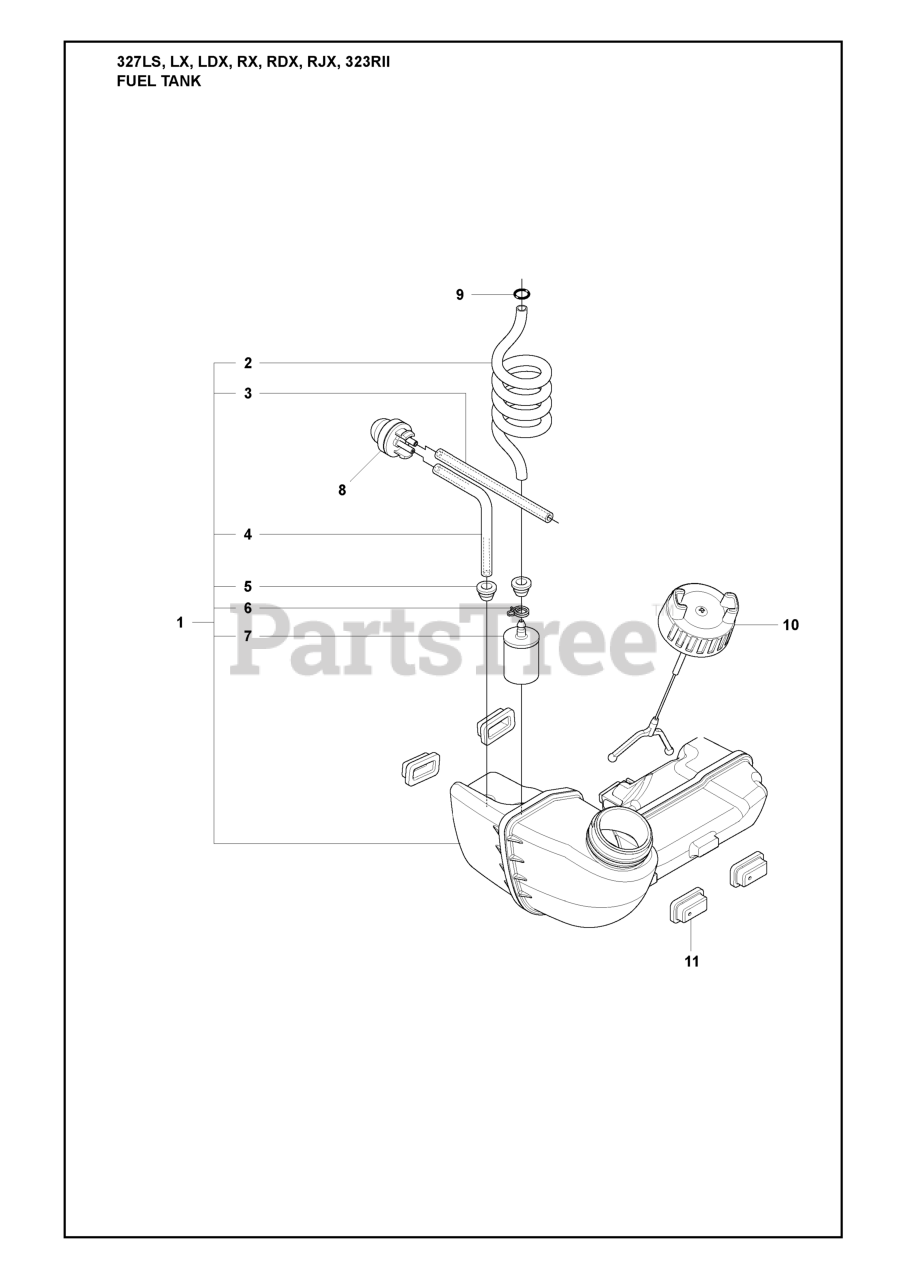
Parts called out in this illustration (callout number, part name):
1	RP FUEL TANK ASSY
2	FUEL HOSE
3	HOSE.FUEL L=102
4	HOSE.FUEL L=102
5	FUEL TANK BUSHING
6	HOSE CLAMP
7	RP FUEL FILTER
8	AIR PURGE BUBBLE
10	TANK CAP
